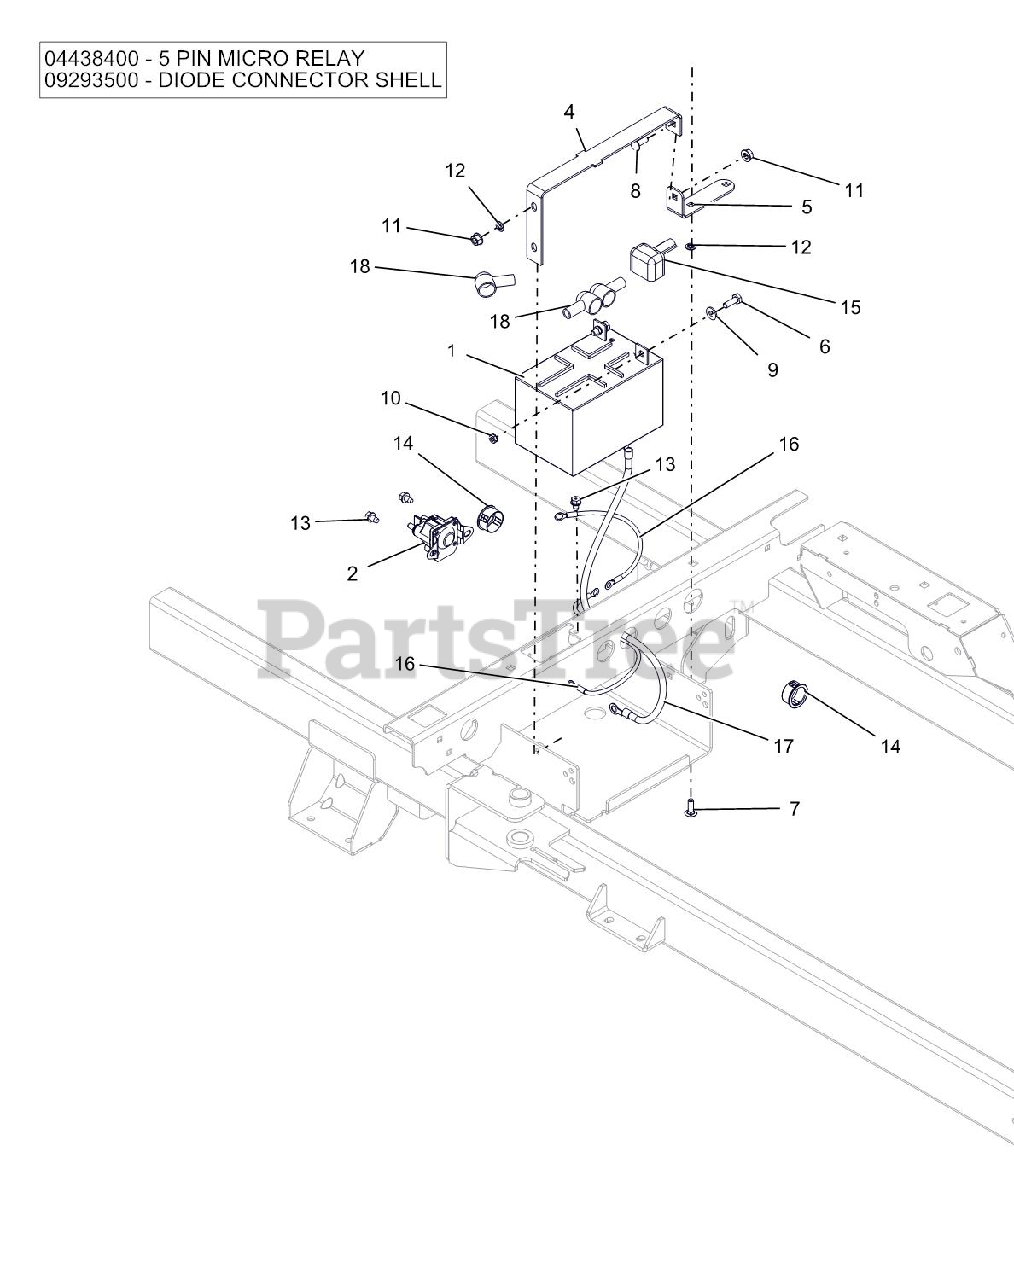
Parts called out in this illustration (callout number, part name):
1	BATTERY, 12V 12A-190CCA
2	SOLENOID, STARTER (SEALED)
4	BRKT, BATTERY HOLD-DOWN
5	BRKT, BATTERY HOLD DOWN
6	@BLT-HEX .25-20X.75 GR5 YWZC
7	@BLT-RDHDSQNK .25-20X.75 G5YZ
8	@BLT-RDHDSQNK .25-20X.75 G5YZ
9	@WSHR-FL-STL.281X.62X.065 YWZC
10	NUT, 10-24 KEPS
11	@NUT-LK-TOP-FLG .25-20 YWZC
12	NUT-PUSH .25X.50 O.D.
13	@SCR-TAP .25-20X.37 HWH YWZ TR
14	BSHG, PANEL SNAP .937X1.11X.56
15	INSULATOR
16	CABLE,POS W/2 1/4 RING 15.0 LG
17	CABLE-NEGATIVE BATTERY 24.00"
18	BOOT, EYELET TERMINAL
19	RELAY,MICRO5 TERML W/RESISTOR
20	DIODE, CONNECTOR SHELL
